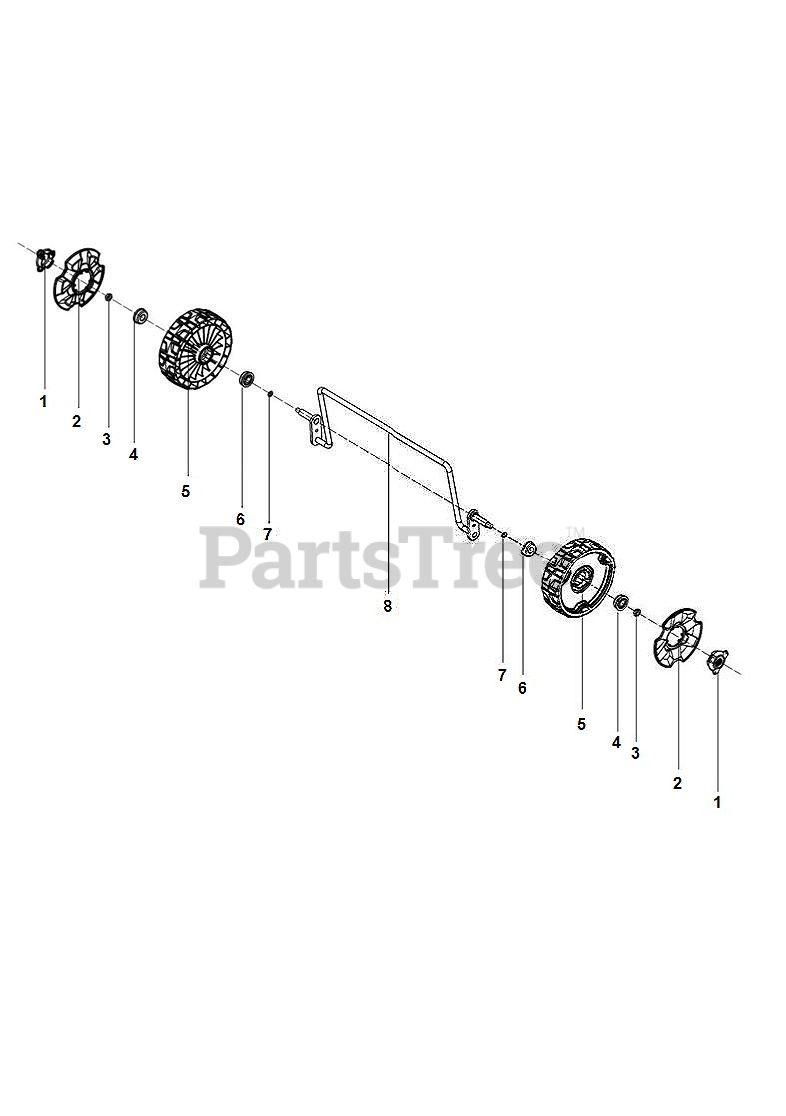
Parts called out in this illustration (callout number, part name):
1	WHEEL COVER 6" #25340700101
3	LOCKING BOLT M8,GB6187.1 #2680
7	WASHER Ï?12 #26800706202
